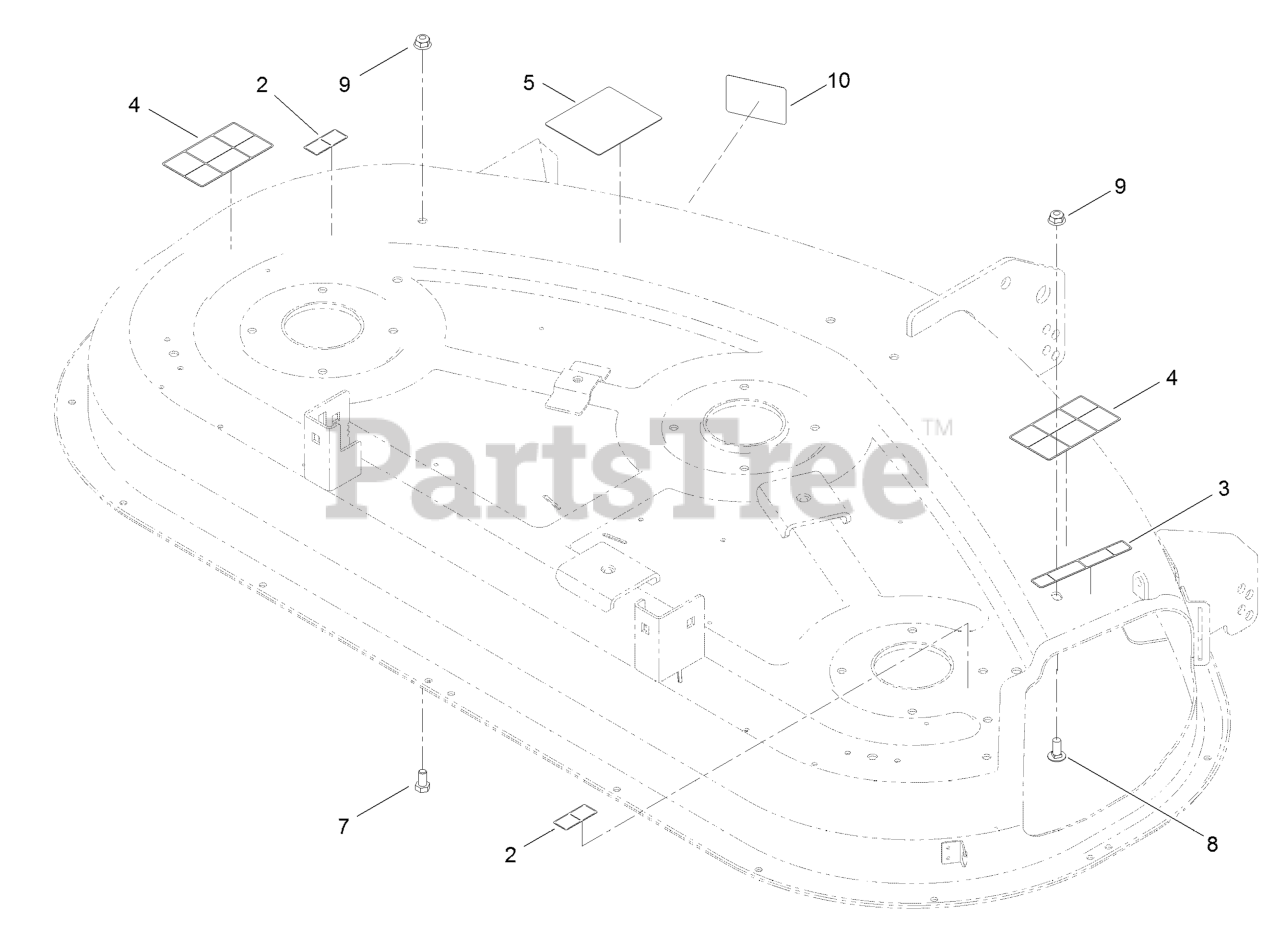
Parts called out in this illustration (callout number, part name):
2	DECAL-DANGER
3	DECAL-DANGER
4	DECAL-DANGER
5	DECAL-ROUTING, BELT
7	SCREW-HH
8	SCREW-CARR
9	NUT-HF, NI
10	DECAL-SCALP, ANTI
